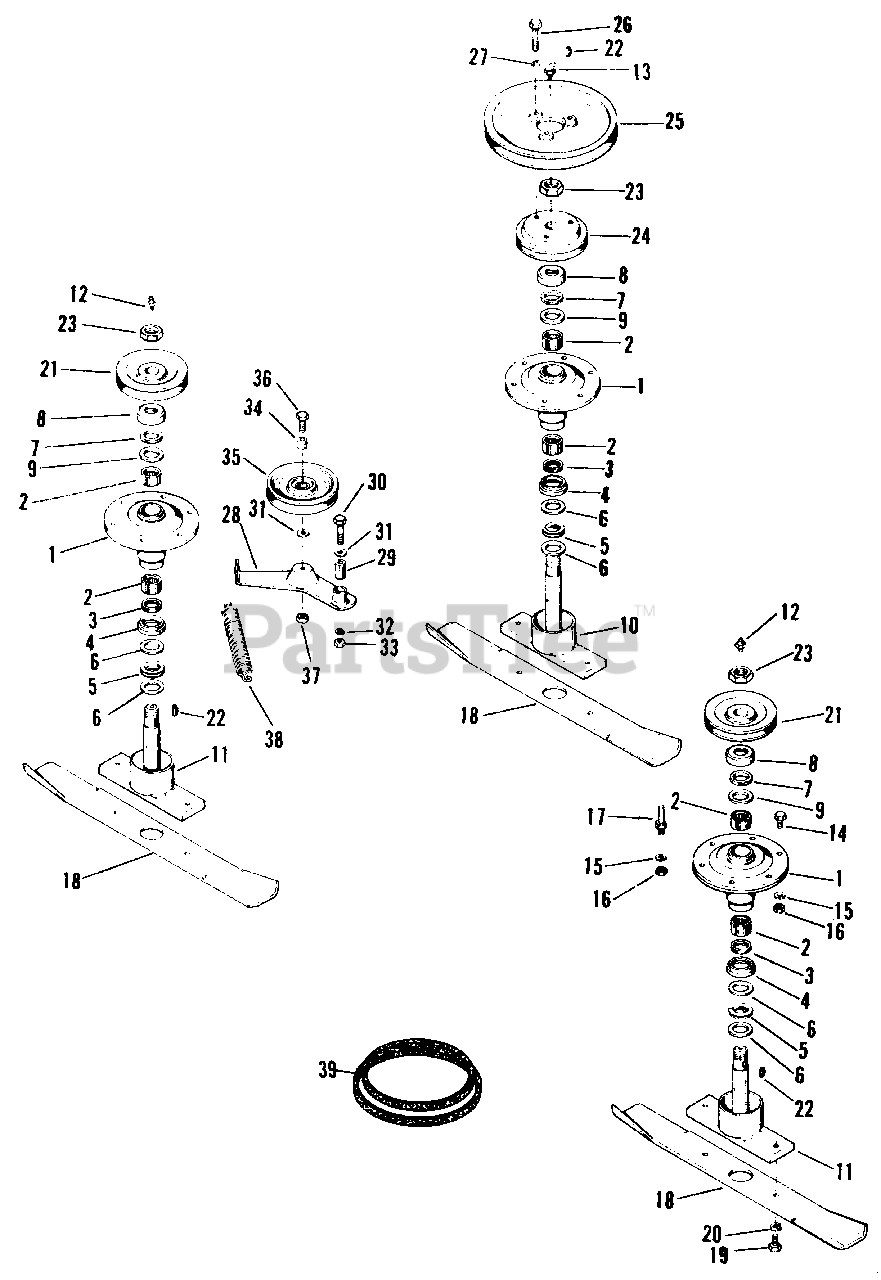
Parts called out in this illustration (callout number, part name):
1	Arbor Tube Assembly
2	Roller Bearing
7	Thrust Bearing
9	Thrust Washer
10	Center Arbor Assembly
11	Side Arbors Assembly
12	Grease Fitting
13	Grease Fitting
14	Hex Capscrew, 3/8"-16 x 1" lg.
15	Lock Washer, 3/8"
16	Hex Nut, Full, 3/8"-16
19	Hex Capscrew, 3/8"-16 x 1" lg.
20	Lock Washer, 3/8"
23	Hex Nut, Jam, Lock, 7/8"
26	Hex Capscrew, 3/8"-16 x 2"
27	Lock Washer, 3/8"
28	Idler Lever Assembly
30	Hex Capscrew, 3/8"-16 x 1-3/4" lg.
31	Plain Washer, 5/16"
32	Lock Washer, 3/8"
33	Hex Nut, Full, 3/8"-16
35	Idler Pulley
36	Special Screw
37	Hex Nut, Jam, Lock, 3/8"-16
39	V-BELT, 116.1"
